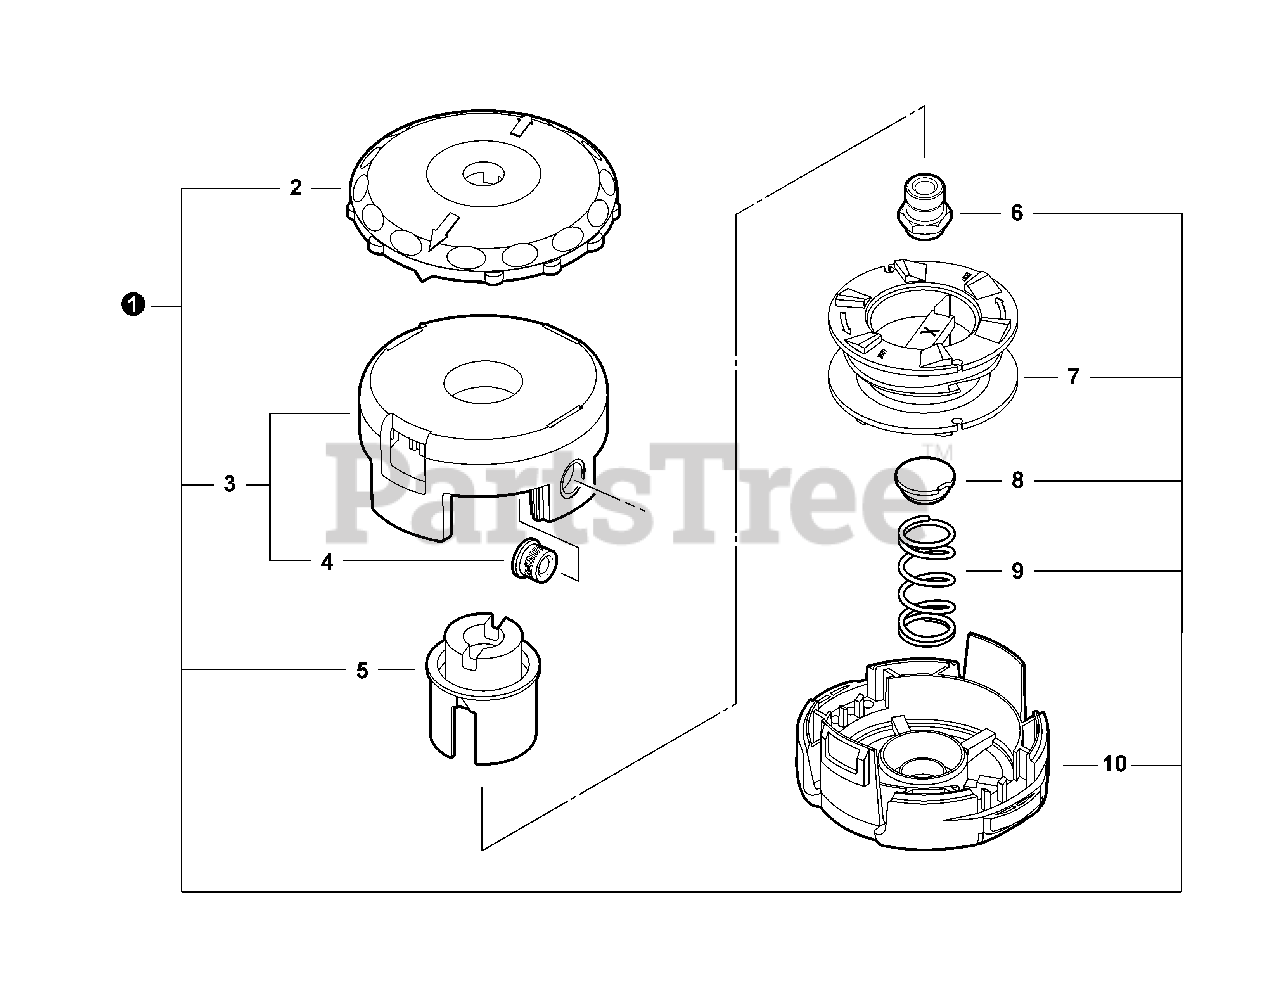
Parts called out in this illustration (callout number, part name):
1	SPEED-FEED 400 TRIMMER HEAD
3	SPOOL HOUSING ASY
5	HUB - BLACK -- LEFT HAND
6	ARBOR - GOLD -- LEFT HAND
8	CAP, SPRING
